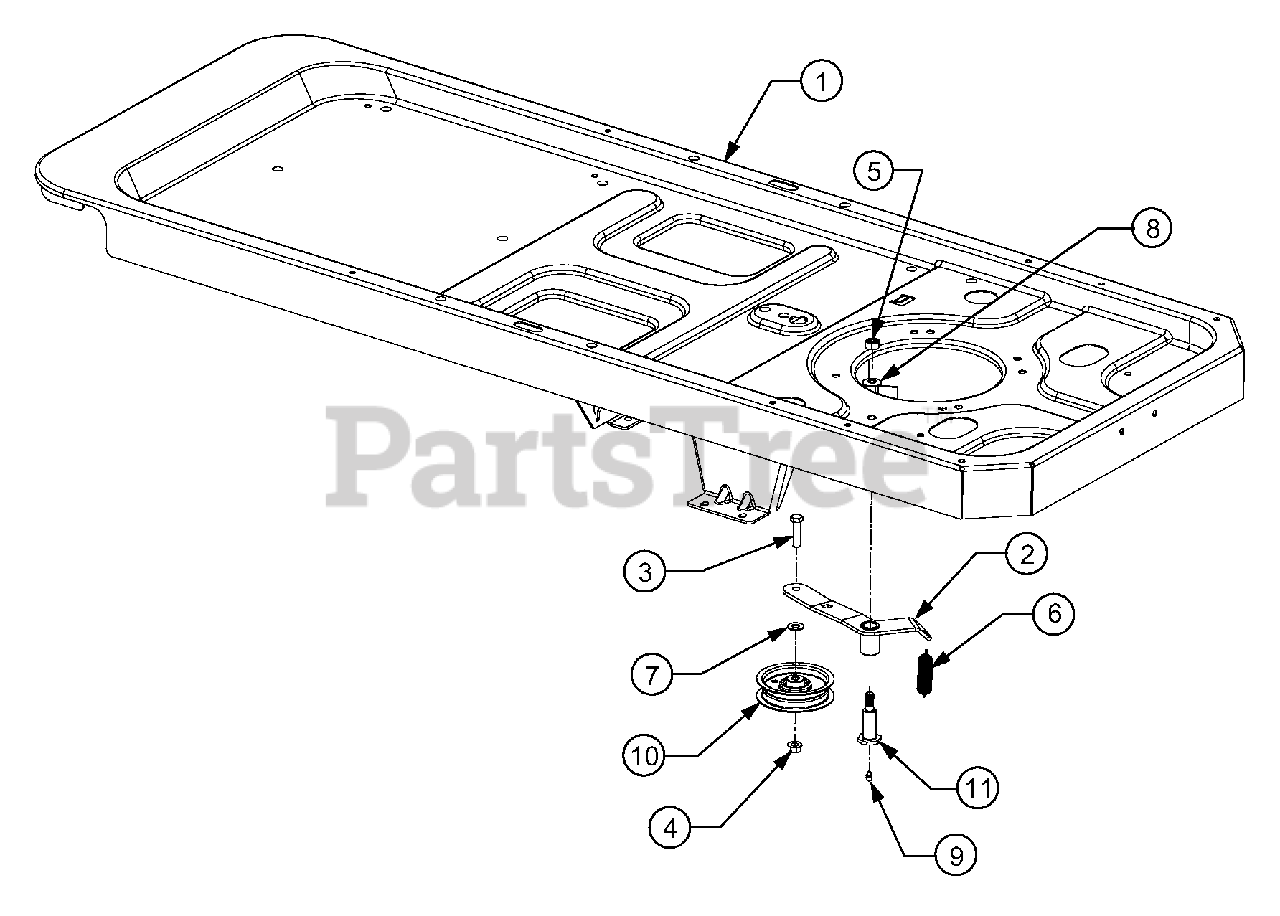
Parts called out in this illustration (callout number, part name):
4	Nut, Hex Flange Lock, 3/-16 GRF
5	Nut, Hex Lock, 7/16-14 GRA
6	Spring, Extension, .75 x 5.06
7	Washer, Flat, .406 x .875 x .059
8	Washer, Flat, .45 x 1.25 x .164 HT
9	Fitting, Lube, 3/16 Drive
10	Screw, Shoulder, .68 x 1.59
11	Pulley, Idler, 3.50 Dia.
